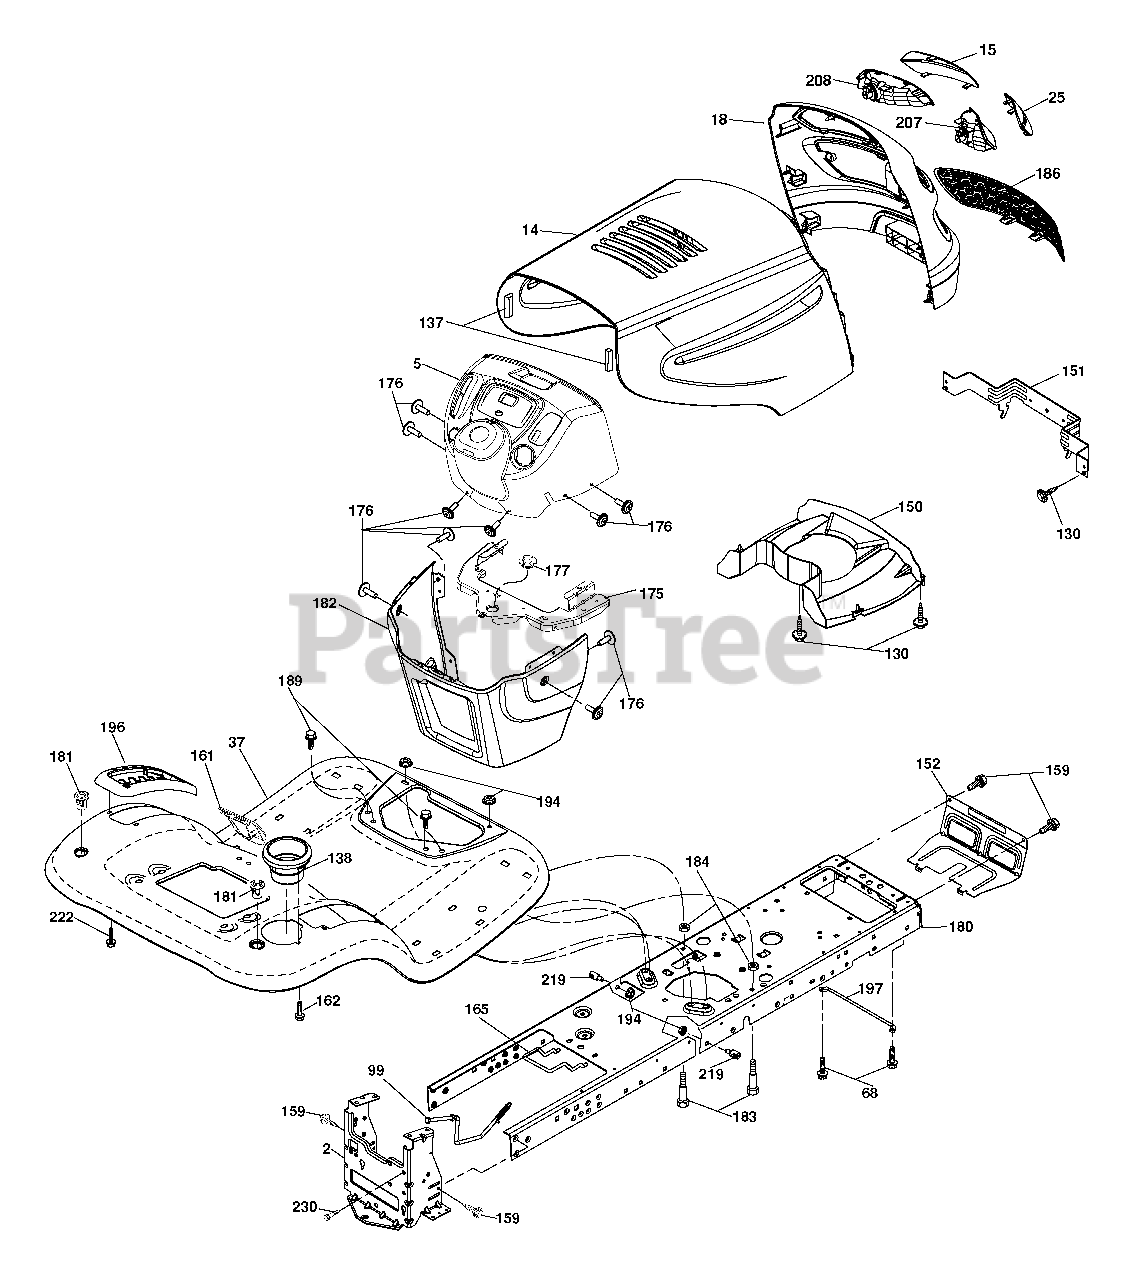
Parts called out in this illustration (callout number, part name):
2	Drawbar
5	Dash
14	Hood
15	Lens Grille LH
18	Grille
25	Lens Grille RH
37	Fender
68	Screw THDROL 5/16-18 x 1/2
99	Rod Bypass Asm
130	Screw 10 x 3/4 Single Lead-Hex
137	Bumper Hood
138	Cupholder
150	Duct Heat Hood
151	Bracket Pivot
152	Shield Browning/Debris
159	Screw Hexwsh Thdrol 3/8-16 x 3/4
162	Screw Hex Wsh Hi-Lo 1/4 x 1/2 unc
175	Crossmember
176	Screw 10-24 x 5/8 Wshd Qdrx
177	Bushing Steering
181	Bushing Mtg. Fender Crgo.
182	Dash Lower
183	Bolt Fin Hex 5/16-18 x 1-1/4
184	Spacer Fender
189	Screw 5/16-18 x 3/4
194	Nut Lock Hex Flange 5/16-18
196	Console Asm. Deck Lift
197	Rod Pivot Chassis
207	Bezel RH
208	Bezel LH
219	Stud Fastener
222	Screw thd Roll 1/4-20 x 5/8
230	Bolt Shoulder 5/16-18
